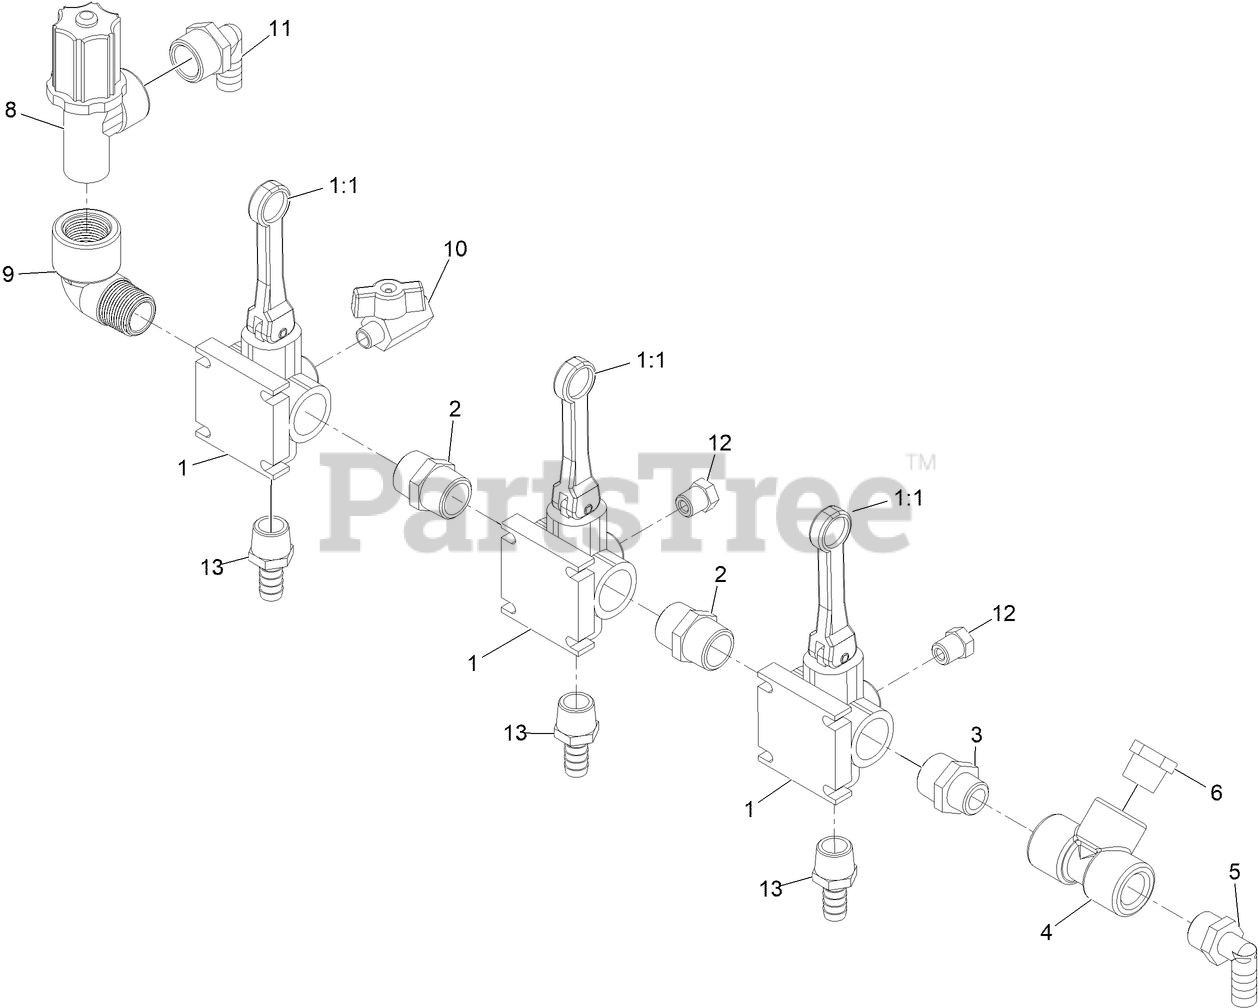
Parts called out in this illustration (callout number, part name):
1	VALVE-DIRECTO
1:1	VALVE HANDLE ONLY AA6B
2	FITTING-NIPPLE
3	FITTING-NIPPLE
5	FITTING-ELBOW, HOSEBARB
6	FITTING-REDUCER
8	VALVE-THROTTLE
9	ELBOW-90DEG
10	VALVE-CHROME, 1/4
11	FITTING-ELBOW, 90
12	PLUG-VALVE
13	FITTING-HOSEBARB
